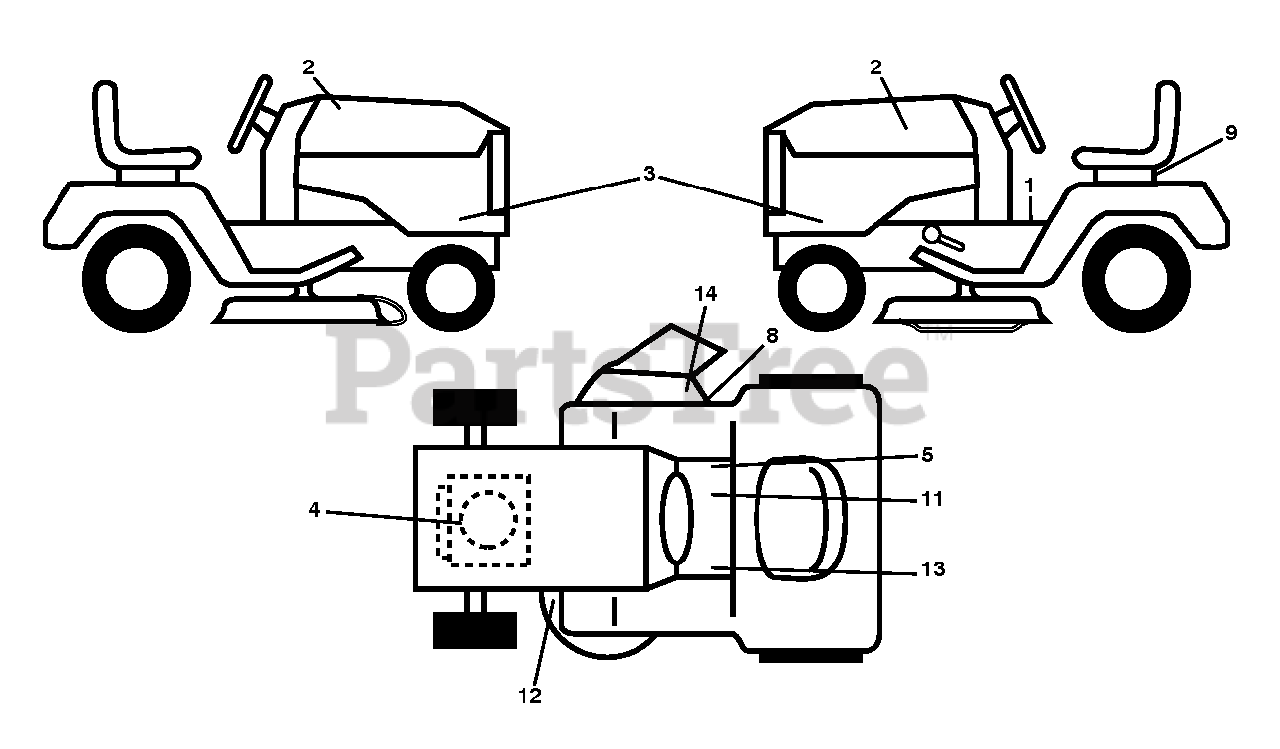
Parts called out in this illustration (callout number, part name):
1	DECAL.READ.OWN.MAN.SYMBOL.LT
2	DECAL.BADGE.170MM.TEXTLOGO.
3	Decal, Side Panel GT2 Set YTH20K42
4	DECAL.ENGINE.WARNING
5	DECAL.PARKING.BRAKE.SADDLE.LT
8	DECAL.DFLCTR.WARNNG.CTFNGR.SYM
9	DECAL BTRY SYMBOLS
11	DECAL.PEDALS.SYMBOL
12	DECAL.V-BELT.SCH.42/46"MEC/ELE
13	DECAL.FNDR.SDLE.BRAKE.CLUTCH.6
14	DECAL.CUTFINGER.CE.02
